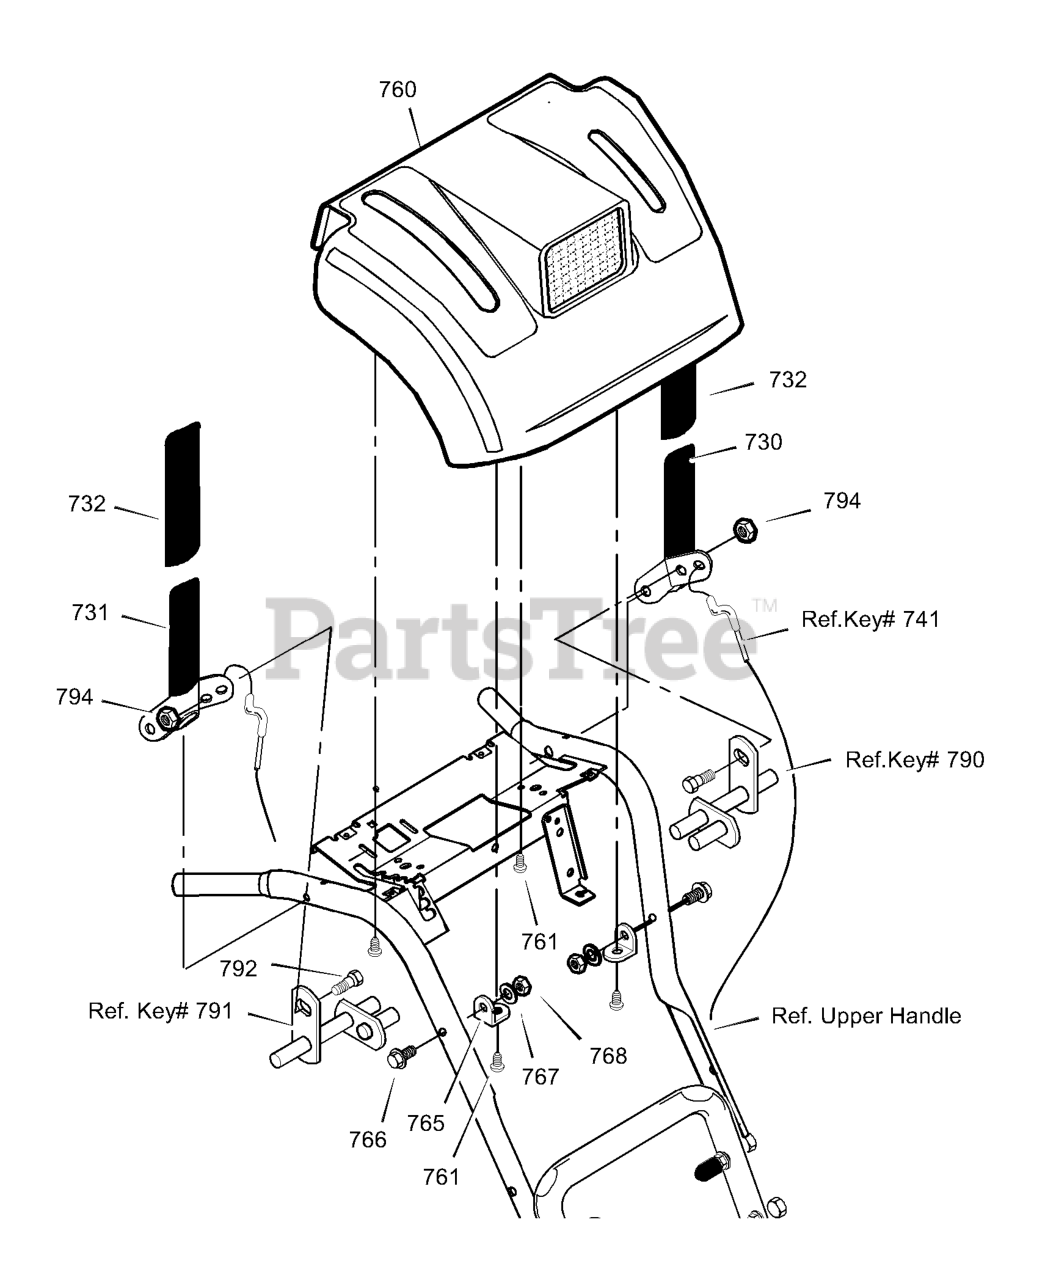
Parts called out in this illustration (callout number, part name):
730	CLUTCH HANDLE LH
731	CLUTCH HANDLE RH
760	PANEL, CONTROL
761	SCREW, 10 X .62
765	BRACKET, PANEL
766	SCREW, 5/16-18 x 1.75
767	WASHER
768	NUT, 5/16-18
792	BOLT, 1/4-20 X .50
794	NUT, 1/4-20
